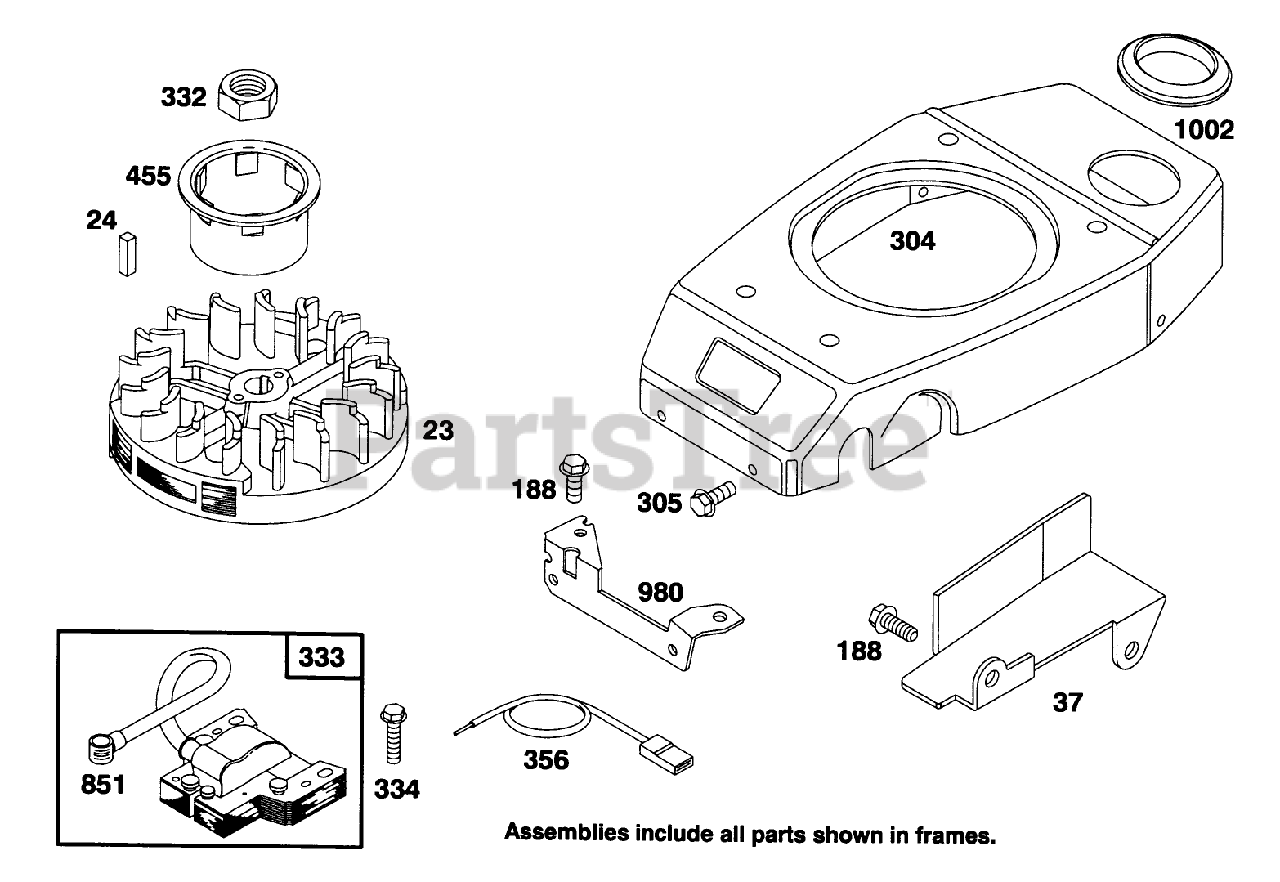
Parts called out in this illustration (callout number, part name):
24	KEY - FLYWHEEL
37	GUARD - FLYWHEEL
188	SCREW - SEM
304	HOUSING - BLOWER
305	SCREW - HEX HEAD
332	NUT - HEXAGON
356	WIRE - GROUND
980	BRACKET-BLOWER HSG
